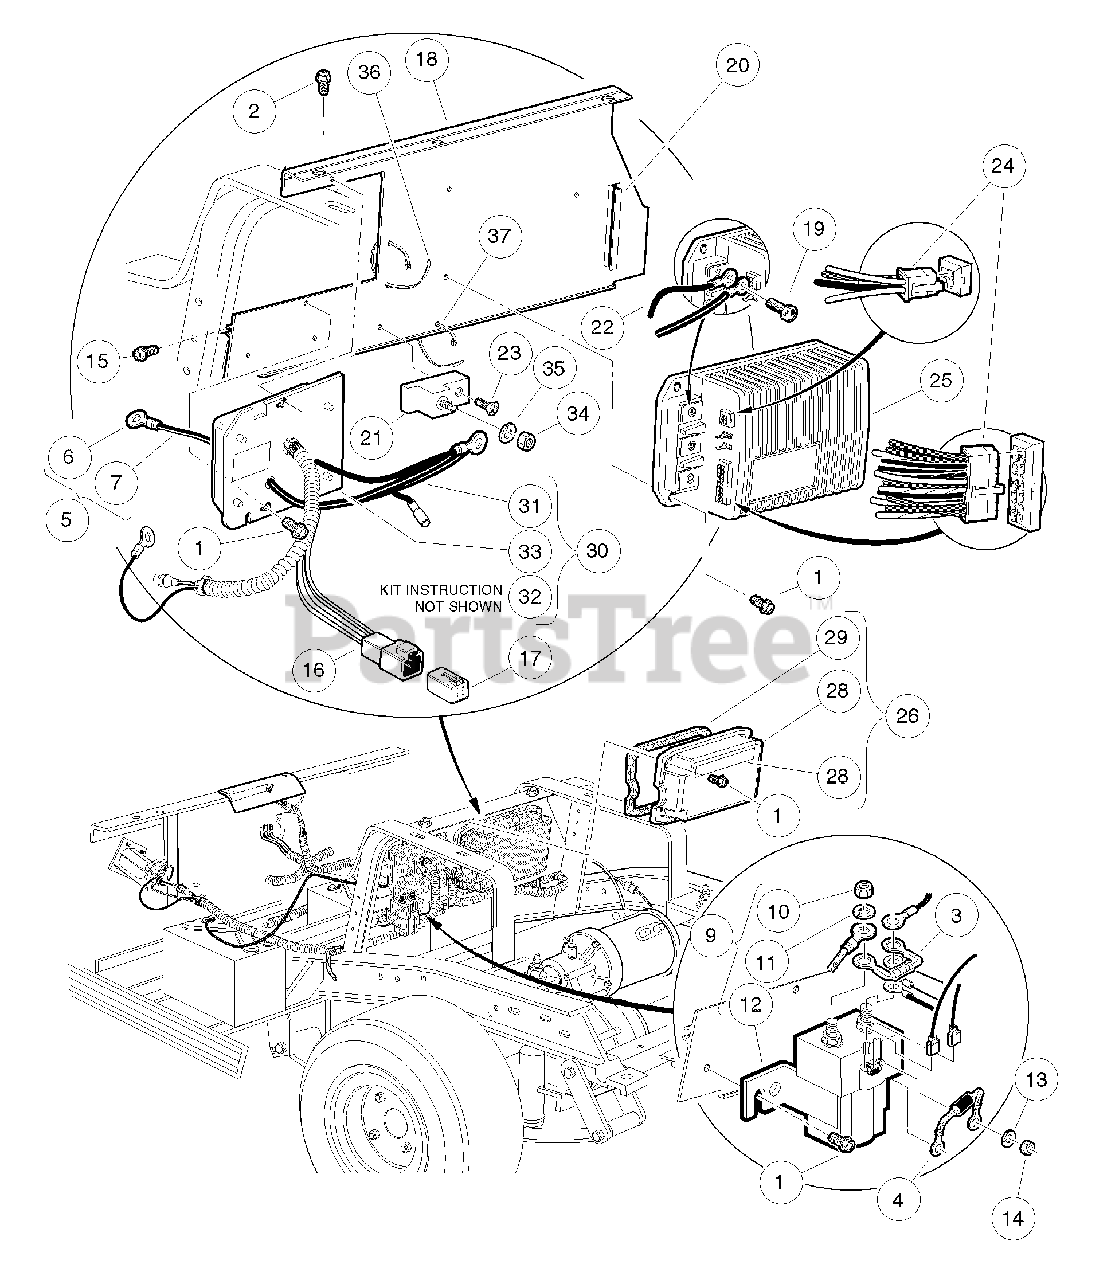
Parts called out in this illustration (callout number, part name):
1	Screw, 1/4 X 0.625 Hex-Head
2	Screw, 5/16-18 X 0.75 Thread-Forming
3	Resistor Assembly
5	Ground Wire Kit, 48-Volt
6	Compression Lug
7	Wire Assembly, Black
8	Tie Wrap, 8" Nylon
9	Solenoid, 48-Volt
10	Nut, M8-1.25 Hex
11	Lockwasher, 8mm Split
13	Washer, Lock
14	Nut
15	Screw, 5/16-18 X 1.25 Thrd Frm
16	Kit, 6-Pin Wedge Lock
17	Kit, 6-Pin Receptacle and Wedge Lock
18	Plate, Component Mounting
19	Bolt, Controller, Terminal
20	Extrusion, Cover Support
21	Terminal Block
22	Wire Assy, #10 Black
23	Screw, #10-24 X 0.75 Phillips, Thread-Forming
24	Kit, Connector, IQ Controller
25	Controller, IQ, 48-volt
26	Cover Asm - Controller
27	Decal, Component Cover
28	Cover - Controller, Deep
29	Gasket - Controller Cover
30	Kit, OBC, DS and Util IQ
31	Asm Wire #10blk Ground
32	Instr Obc Ds Pre 01-28-2007
34	Nut, 5/16-18 Hex
35	Lockwasher, 5/16 Split
36	Tie Wrap, 11" Nylon
37	Tie Wrap, 8" Nylon
